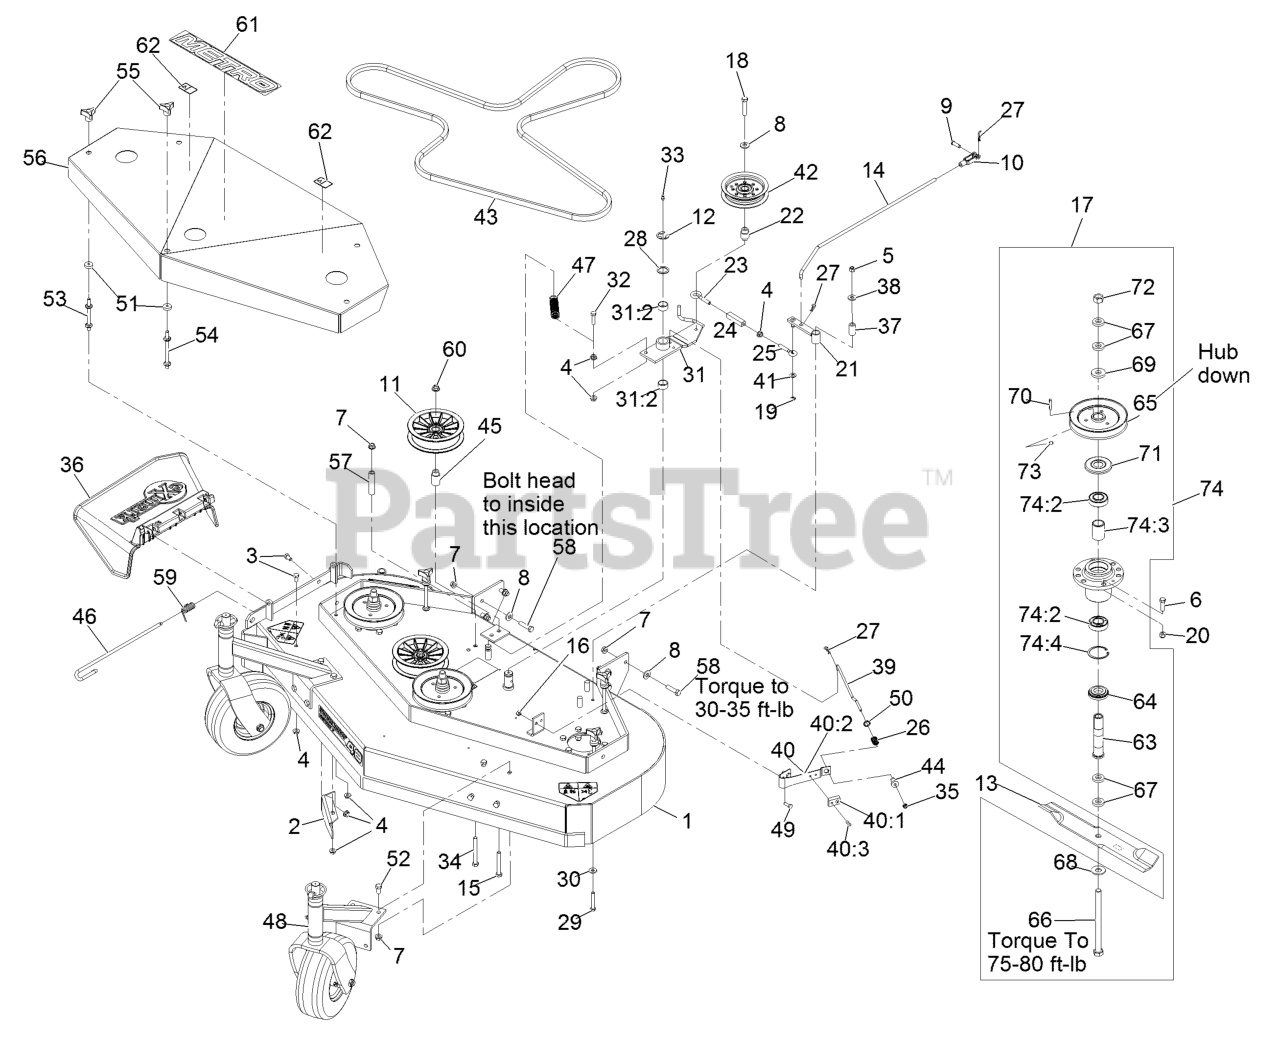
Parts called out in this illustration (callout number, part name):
1	DECK-SERVICE, 48
2	BAFFLE-DOGLEG
3	SCREW-HH
5	NUT-LOCK, NI
6	SCREW-HH
7	NUT-HHF, WHIZ
8	WASHER-BELLEVILLE
9	PIN-CLEVIS
10	YOKE-ADJUSTABLE
11	PULLEY,IDLER 5"
12	RING-RETAINING, EXT
14	ARM-ASSIST, LINKAGE
15	SCREW-HH
16	NUT-LOCK, NI
17	ASM, CUTTER HOUSING OUTER
18	SCREW-HH
19	RING-RETAINING, EXT
20	NUT-LOCK, NI
21	ARM-ASSIST, 32/36
22	BUSHING-ENGAGEMENT
23	EYEBOLT-THREAD, LH
24	BODY-TURNBUCKLE
25	EYEBOLT-THREAD, RH
26	SPRING-COMPRESSION
27	PIN-COTTER
28	WASHER-SPINDLE
29	SCREW-HH
30	WASHER-SPRING
31	IDLER ARM ASM
31:2	SLEEVE-BEARING
32	SCREW-HH, SPECIAL
33	FITTING-GREASE
34	SCREW-HH
35	NUT-LOCK, NI
36	CHUTE DEFLECTOR XRK M056
37	TUBE-PIVOT
38	WASHER-FLAT
39	ROD-BRAKE
40	PAD AND SPRING ASM
40:1	PAD-BRAKE
40:3	RIVET-POP
41	WASHER-PLAIN
43	BELT,BLADE 48
44	SPACER-FLANGED
45	BUSHING-IDLER
46	PIN-CHUTE
47	SPRING-EXTENSION
48	ASM-CASTER MNT W/WEIGHT
49	SCREW-HH
50	RING-PUSH ON
52	SCREW-HH
53	STUD-SHIELD, BELT (SHORT)
54	STUD-SHIELD, BELT (LONG)
55	KNOB-3 PRONG
56	ASM,SHIELD W/DECALS 48 ME
58	SCREW-HH
59	SPRING, TORSION
60	NUT-HF, NI
61	Decal-Metro
62	DECAL-WARNING
63	TUBE-SPINDLE, SHORT
64	SPACER-GUARD, BOTTOM
65	SHEAVE
66	SCREW-CAP, HH
68	WASHER-SPRING
69	WASHER-RETAINER, SHEAVE
71	GUARD-BEARING, TOP
72	NUT-HEX
73	SETSCREW
74	Cutter Housing ASM
74	KIT, CUTTER HOUSING
74:2	BEARING-JACKSHAFT
74:3	SPACER-BEARING
74:4	RING-SNAP
